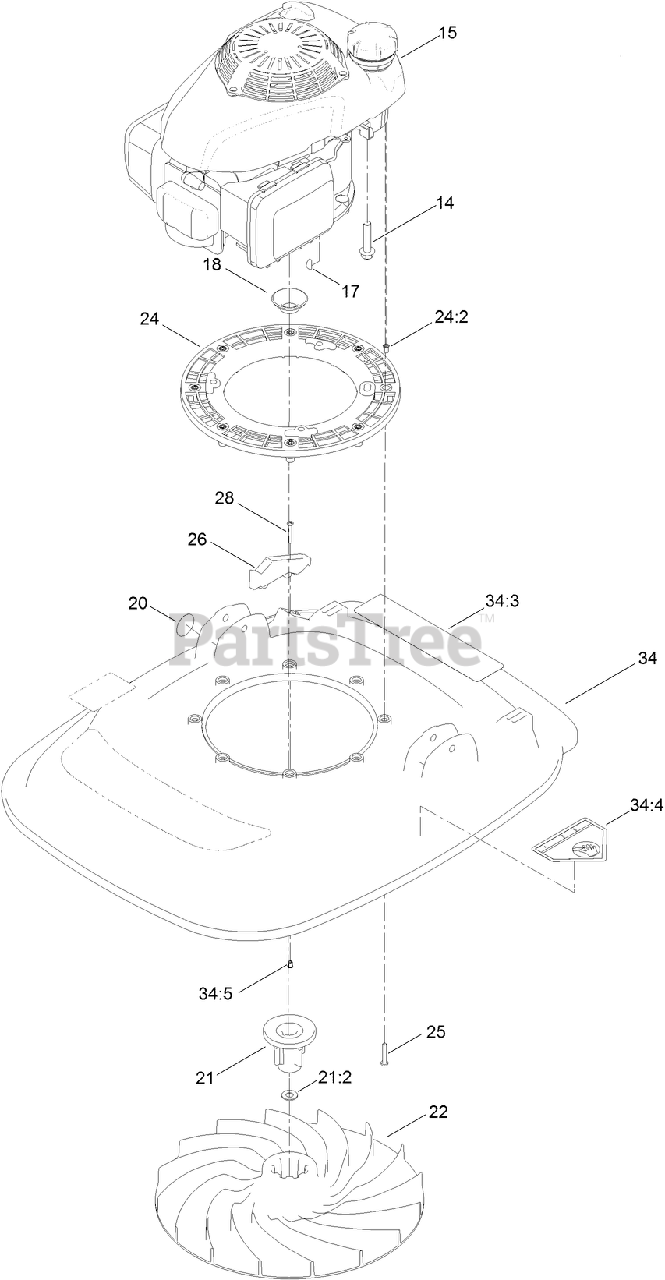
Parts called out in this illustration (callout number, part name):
14	SCREW-TAPTITE
15	ENGINE-HONDA
17	KEY-WOODRUFF
18	PROTECTOR-SEAL, OIL
20	DECAL
21	DRIVE AND SPACER ASM
21:2	WASHER-PLAIN
22	IMPELLER
24	FRAME-ENGINE
24:2	INSERT-BRASS
25	SET-SCREW
26	BRACKET
28	SCREW
34	DECK ASM
34:3	DECAL-WARNING
34:4	DECAL-DANGER
34:5	INSERT
